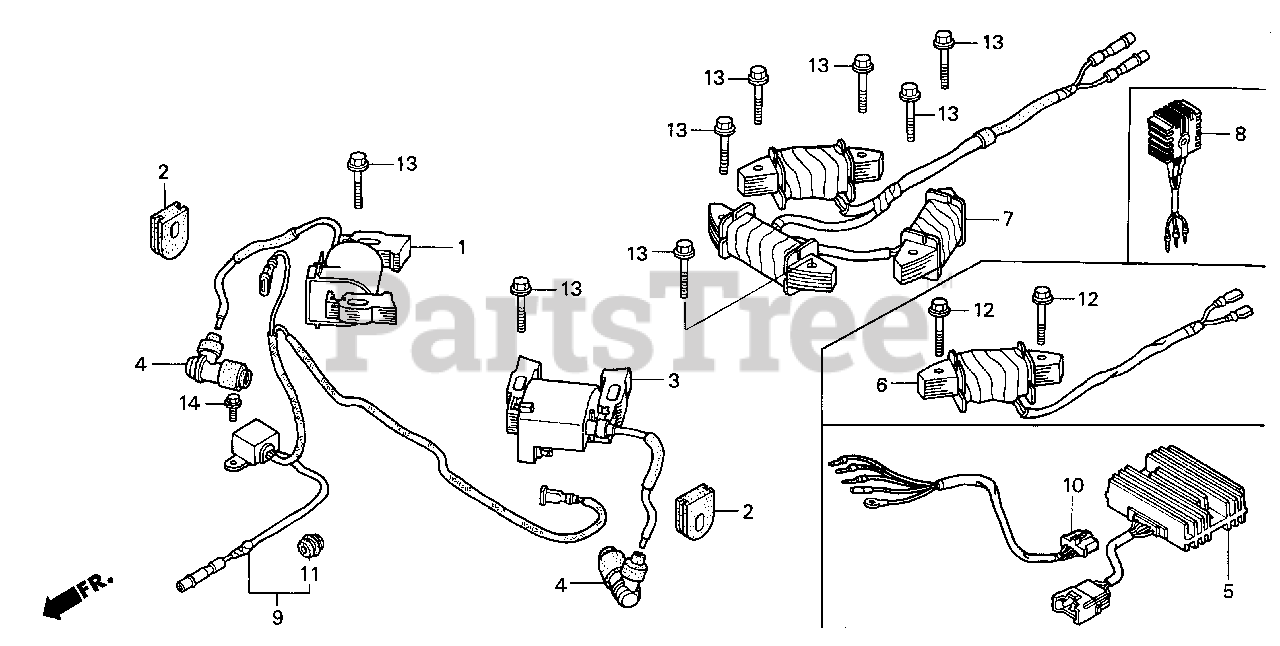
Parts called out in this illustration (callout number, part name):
1	COIL ASSY., R. IGNITION
2	GROMMET, IGNITION WIRE
3	COIL ASSY., L. IGNITION
4	CAP ASSY., NOISE SUPPRESSOR
6	COIL ASSY., CHARGE (12V/3A)
8	RECTIFIER ASSY.
9	DIODE ASSY., ENGINE STOP
11	GROMMET, TOOL
12	BOLT, FLANGE (6X35)
13	BOLT, FLANGE (6X32)
14	BOLT, FLANGE (6X8)
